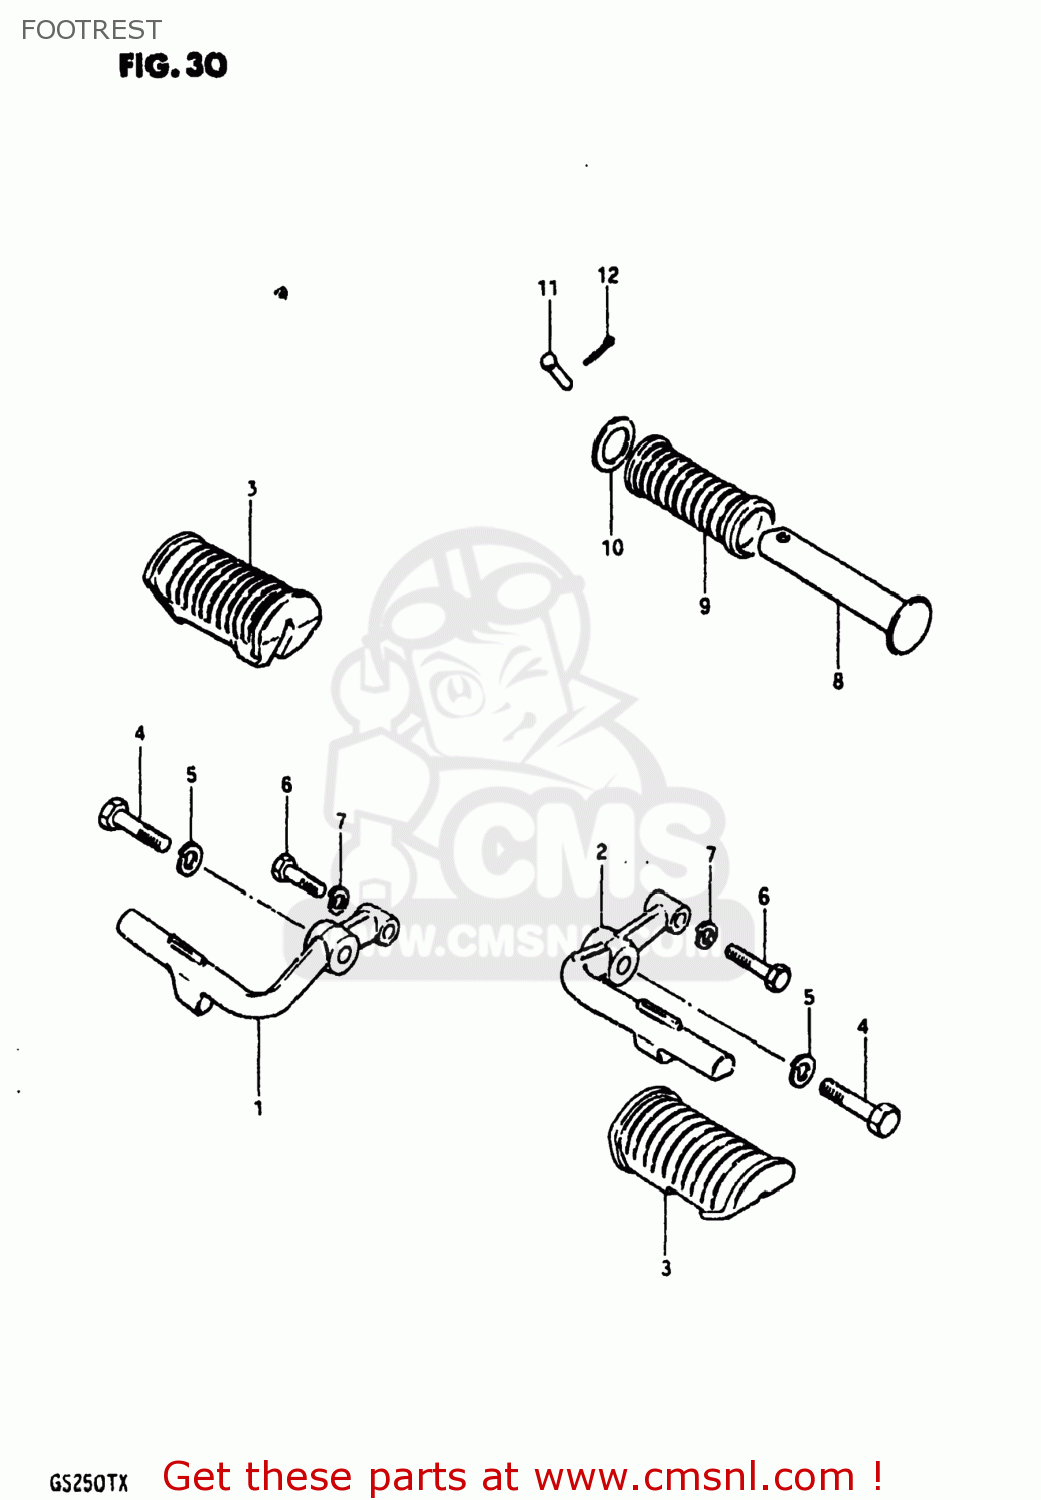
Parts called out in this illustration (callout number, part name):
1	BAR,FRONT FOOTREST,RIGHT
2	BAR,FRONT FOOTREST,LEFT
3	RUBBER,FR FOOTREST
4	BOLT
5	LOCK WASHER
6	BOLT 8X40
7	LOCK WASHER
8	BAR,PILLION FOOTREST
9	RUBBER,PILLION FOOTREST
10	WASHER (19.5X32X2)
11	PIN
12	PIN
